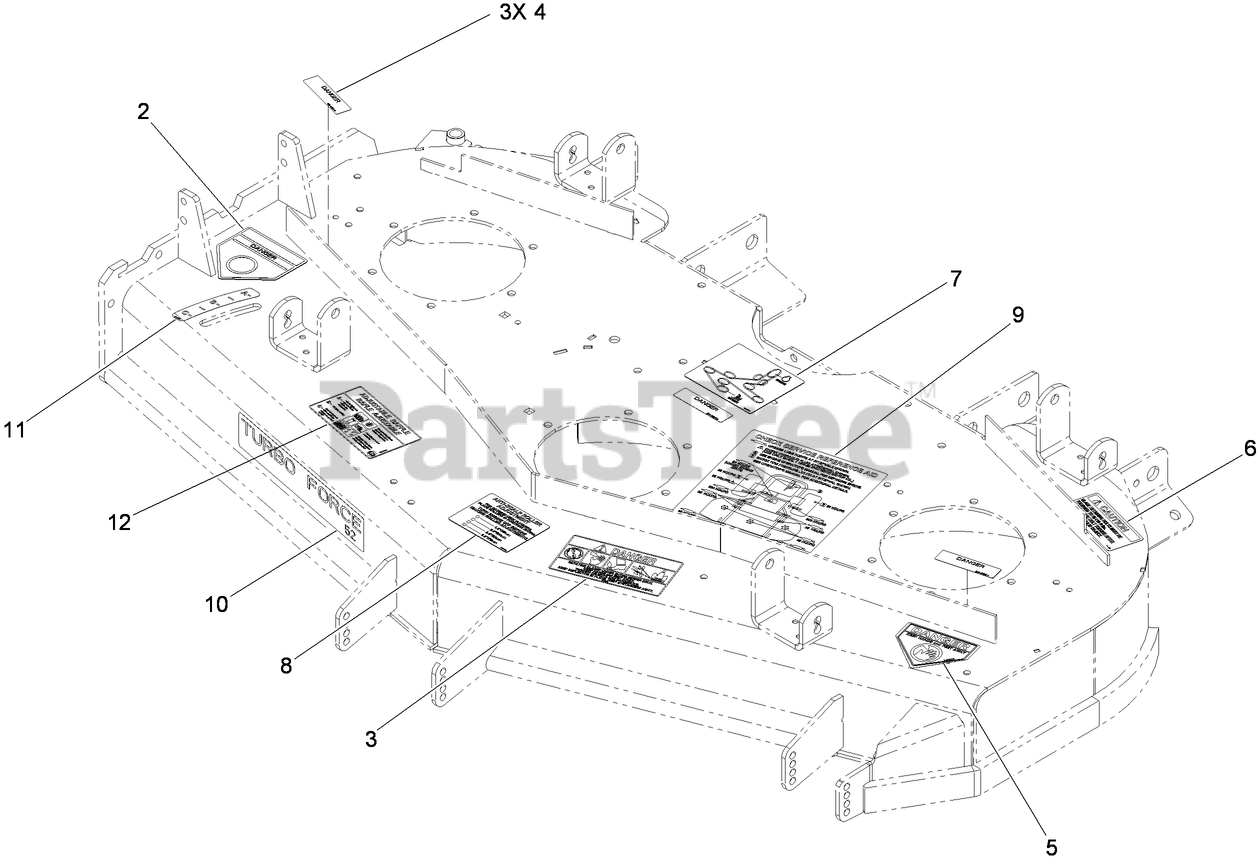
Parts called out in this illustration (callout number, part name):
2	DECAL-DANGER
3	DECAL-DANGER, THROWN OBJECT
4	DECAL-COVER, MISSING
5	DECAL-DANGER
6	DECAL-TORQUE
7	Decal-Routing, Belt
8	DECAL-SCALP, ANTI
9	DECAL-SERVICE, CHECK
11	DECAL-SETTING, BAFFLE
12	DECAL-ADJUSTMENT, BAFFLE
